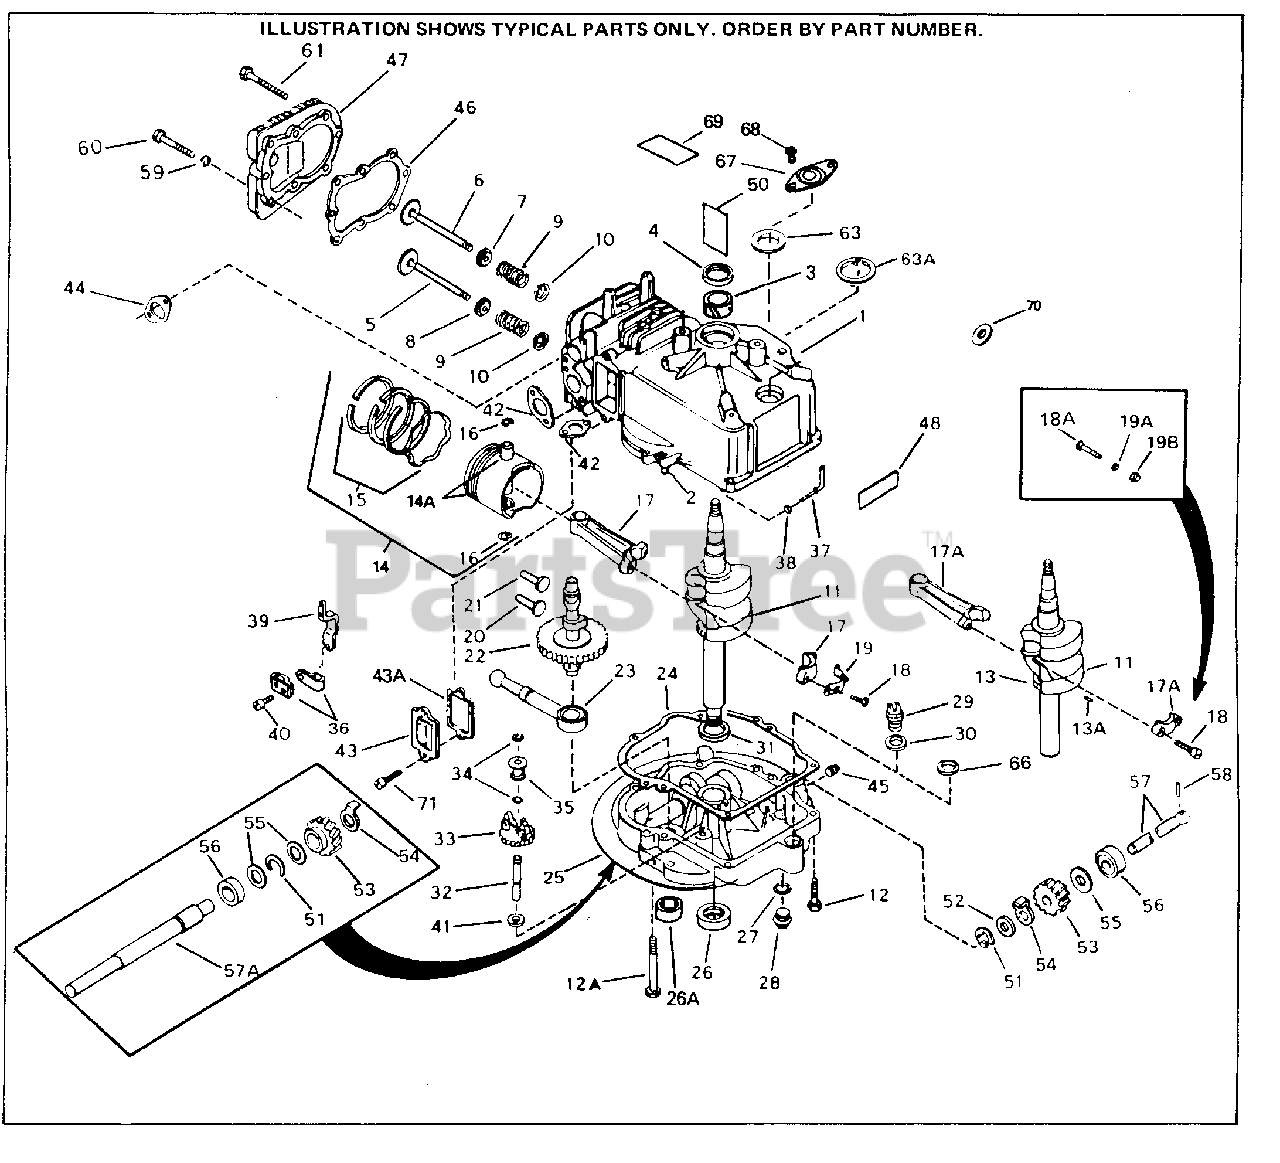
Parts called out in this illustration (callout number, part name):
1	"Cylinder (Incl. 2,4,46,47,48) 2-5/8"B ore
2	Dowel Pin
4	Seal, Oil
5	Intake Valve (Std.) (Incl. 10) Invert ed Ports
5	Intake Valve (1/32" OS)(Incl. 10) Inv .Ports
6	Exhaust Valve (Std.) (Incl. 151)d Por ts)
6	Exhaust Valve (1/32" OS) (Incl. 151)d Ports)
7	Cap, Upper valve spring Early product ion
8	Cap, Upper valve spring Early product ion
9	Spring, Valve
10	Cap, Lower valve spring
11	Crankshaft
12	Screw, 1/4-20 x 1-1/4"
12A	Screw, 1/4-20 x 1-1/4"
13	Crankshaft Gear Early production only
13A	Pin, Crankshaft gear only)
14	Piston, Pin & Ring Set (Std) 2-5/8"Bo re
14	Piston, Pin & Ring Set (.010" OS)
14	Piston, Pin & Ring Set (.020" OS)
14A	Piston & Pin Ass'y. (Std)(Incl. 16) 2 -5/8"
14A	Piston & Pin Ass'y. (.010" OS) Incl. 16
14A	Piston & Pin Ass'y. (.020" OS) Incl. 16
15	Ring Set (Std) (2-5/8" Bore)
15	Ring Set (.010" OS)
15	Ring Set (.020" OS)
16	Piston Pin Retaining Ring
17	Rod Assy., Connecting (Incl. 18)
18	Bolt, Connecting rod
18A	Connecting Rod Bolt Early production
19	Locking Plate (Early production)
19A	Connecting Rod Bolt Washer Early prod uction
19B	Lock Nut (Early production)
20	Lifter, Intake valve
21	Valve Lifter
22	Camshaft (MCR)
23	Oil Pump Ass'y.
24	Mounting Flange Gasket
25	Mounting Flange Assy. Incl. 26,27,28, 32,45,66
26	Oil Seal
27	Drain Plug Gasket
28	Plug, Oil drain
31	Washer, Thrust
32	Shaft, Mechanical governor
33	Gear Assy., Governor (Incl. 41)
34	Retaining Ring
35	Spool, Governor
36	Clamp, Governor lever
37	Rod Assy., Governor (Incl. 38)
38	Flat Washer
39	Lever, Governor
40	Screw, 8-32 x 5/16"
41	Washer, Flat
42	Gasket, Intake pipe
43A	Gasket, Breather
44	Intake Pipe Gasket
45	Oil Drain Plug (1/8-27 Sq.hd.) As req uired
46	Gasket, Cylinder head
47	Cylinder Head Not included with short block
48	Decal, Model & Serial Number
50	Decal, Instruction
58	Pin, P.T.O. shaft (Use as required)
59	Washer tion)
60	Screw, 5/16-18 x 1-1/2" As req.,notw/ 26073
61	Screw, 5/16-18 x 2" (Use as required)
63	Breather Gasket (Use as required) Top Mount
67	Cover, Breather (Use as required)
68	Screw, 10-24 x 9/16"
69	Decal, Name
